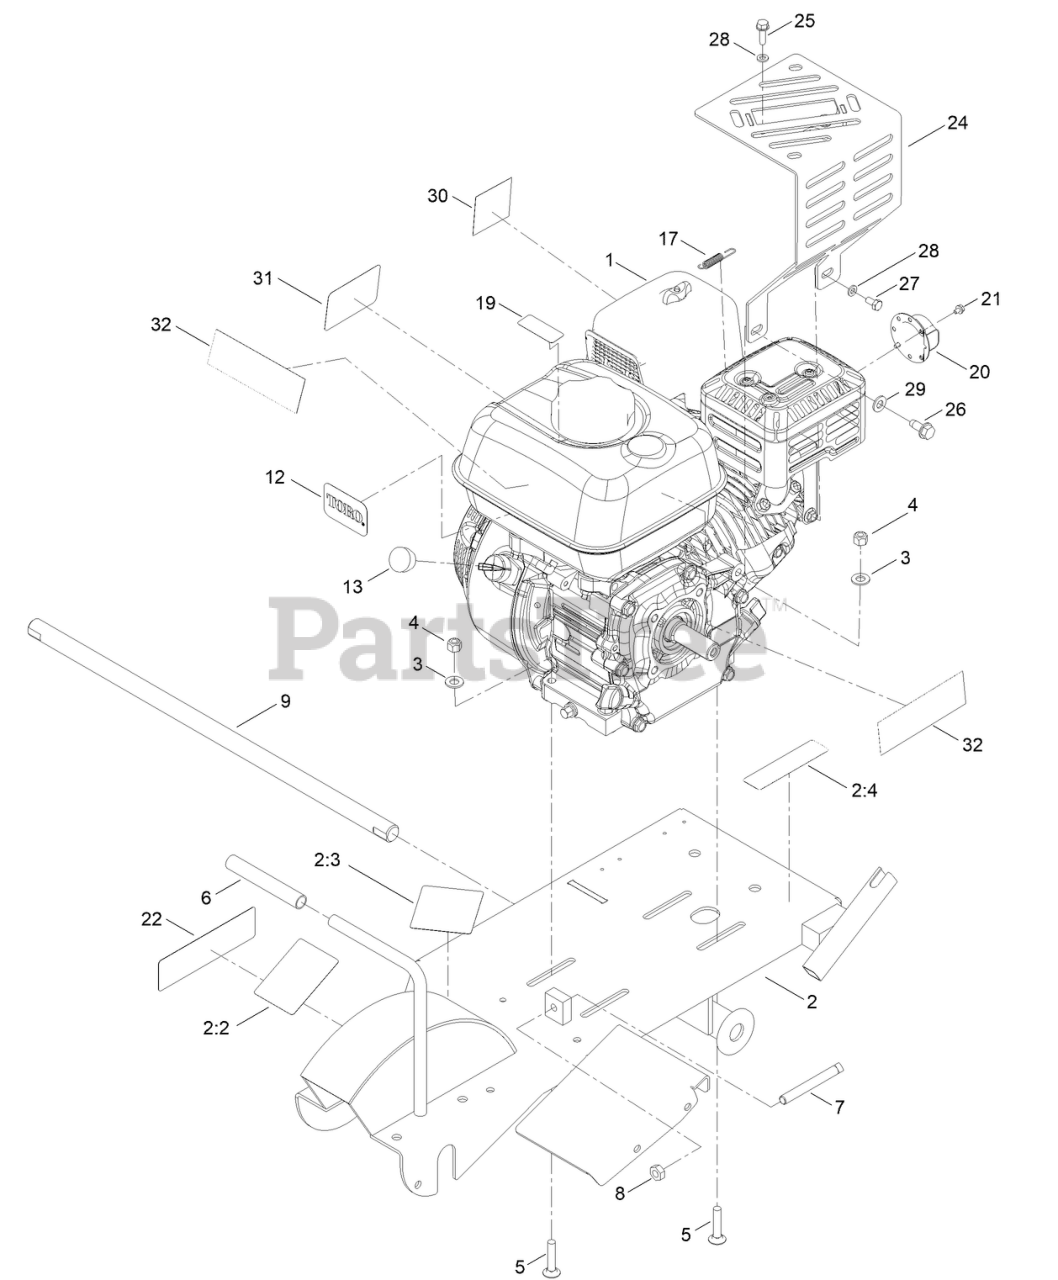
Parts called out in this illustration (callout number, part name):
2	FRAME ASM
2:2	DECAL-CAUTION
2:3	DECAL-DANGER
2:4	DECAL-ARRESTOR, SPARK
3	WASHER-FLAT
4	NUT-LOCK, NI
5	BOLT-CARR
6	GRIP-RUBBER
7	SCREW-SET, SQH
8	NUT-HEX
9	BAR-AXLE, WHEEL
12	DECAL
13	PLUG-ENGINE
17	SPRING-EXTENSION
19	DECAL-WARNING, ETHANOL
20	DEFLECTOR
21	SCREW-HWH
22	DECAL-ROTATE TOOTH
24	GUARD-MUFFLER
26	SCREW-HWHTF
27	SCREW-HH
28	WASHER-FLAT
29	WASHER-PLAIN
30	DECAL-CPER0003
31	DECAL-CPER0011
32	DECAL- RHHLG2X5
